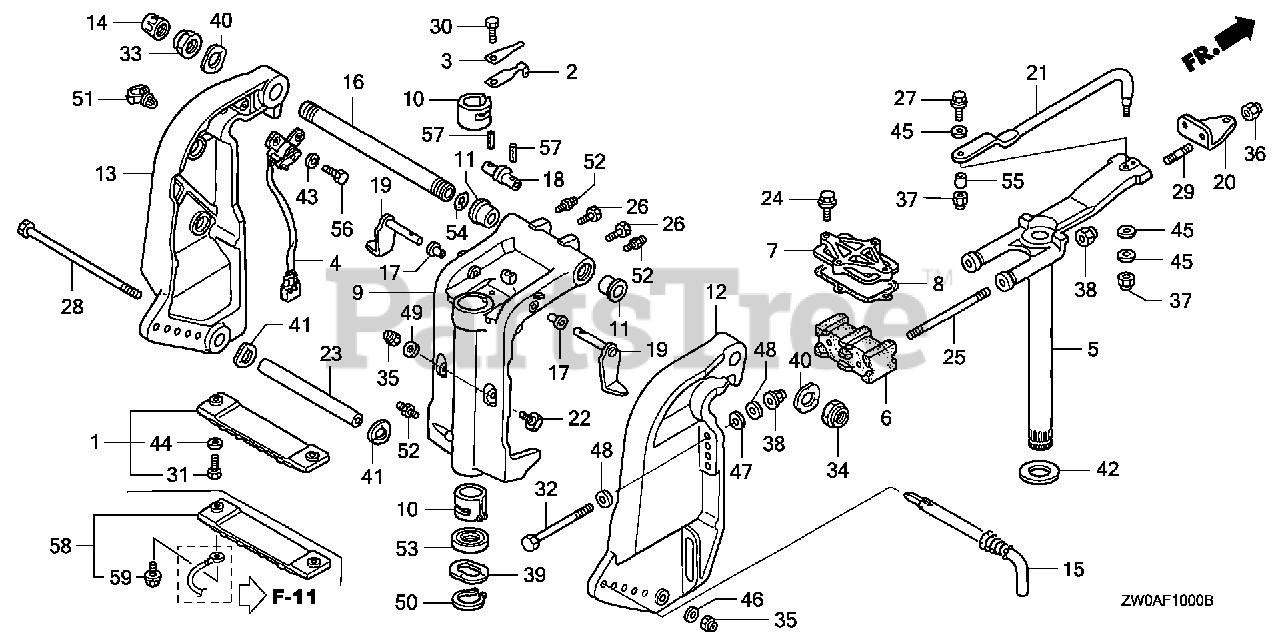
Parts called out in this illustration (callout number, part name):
1	METAL KIT, ANODE
2	SPRING, CLICK
3	SPRING, CLICK ASSIST
4	SENSOR ASSY., TRIM ANGLE
5	FRAME, MOUNTING *NH282MU* (OYSTER SILVER METALLIC-U)
6	MOUNT, RUBBER (UPPER)
7	HOLDER, MOUNTING (UPPER)
8	GASKET, MOUNTING HOLDER (UPPER)
9	CASE, SWIVEL *NH282MU* (OYSTER SILVER METALLIC-U)
10	LINER, SWIVEL CASE
11	BUSH, SWIVEL CASE
12	BRACKET, R. STERN *NH282MU* (OYSTER SILVER METALLIC-U)
13	BRACKET, L. STERN *NH282MU* (OYSTER SILVER METALLIC-U)
14	CAP, TILTING BOLT
15	ROD, ADJUSTING
16	SHAFT, TILTING
17	BUSH, TILT ARM
18	BRACKET, TILTING
19	STOPPER, TILT
20	PLATE, STEERING
21	ROD, STEERING
22	RECEIVER, THRUST
23	COLLAR, CYLINDER (LOWER)
24	BOLT, FLANGE (8X30)
25	BOLT, STUD (12X150)
26	BOLT (1/4-28UNF)
27	BOLT (3/8-24UNF)
28	BOLT, HEX. (10X235)
29	BOLT, STUD (10X28)
30	BOLT, HEX. (6X14)
31	BOLT, HEX. (6X25)
32	BOLT, HEX. (12X119)
33	NUT, SELF-LOCK (7/8-14UNF)
34	NUT, SELF-LOCK (25X2.0)
35	NUT, SELF-LOCK (10MM)
36	NUT, SELF-LOCK (10MM)
37	NUT, SELF-LOCK (3/8-24UNF)
38	NUT, SELF-LOCK (12MM)
39	WASHER, WAVE (40MM)
40	WASHER, WAVE (26MM)
41	WASHER, WAVE (32MM)
42	WASHER, THRUST (34MM)
43	WASHER, PLAIN (6MM)
44	WASHER, PLAIN (6MM)
45	WASHER (10MM)
46	WASHER, PLAIN (10MM)
47	WASHER, PLAIN (12MM)
48	WASHER, PLAIN (12MM)
49	WASHER, PLAIN (10MM)
50	CIRCLIP (OUTER) (39MM)
51	CLIP, WIRE HARNESS
52	NIPPLE, GREASE
53	OIL SEAL (39.5X52X6) (ARAI)
54	O-RING (15.54X2.26)
55	COLLAR, STEERING ROD
56	BOLT, HEX. (6X20)
57	PIN, SPRING (2.5X20)
